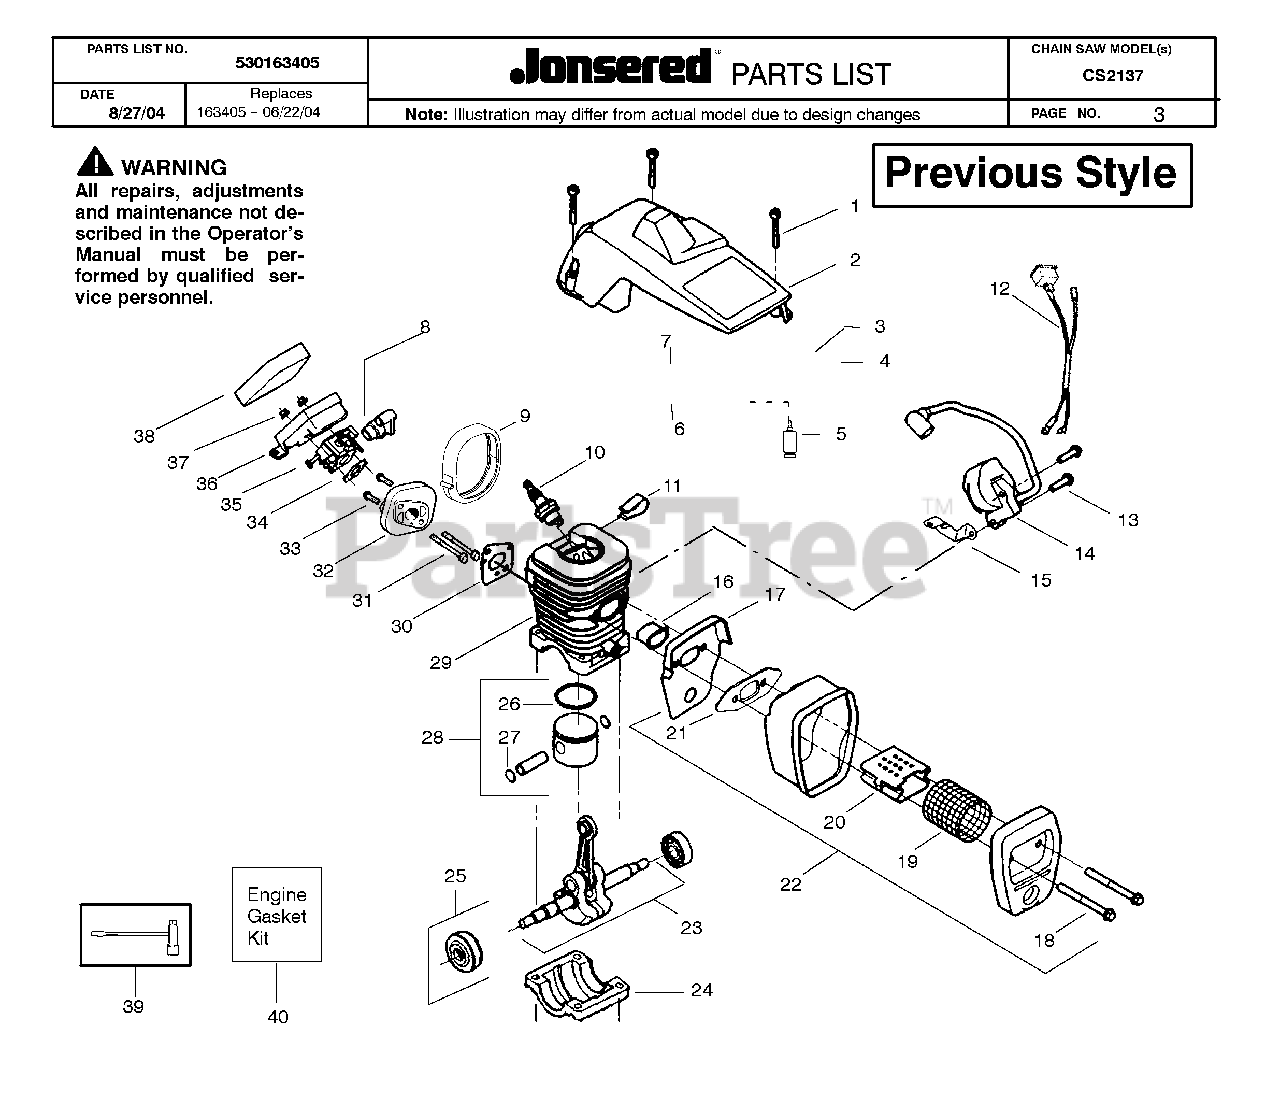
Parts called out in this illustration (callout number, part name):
2	CYL SHIELD ASSY
5	FUEL PICK-UP ASSY
8	GROMMET-CARB ADJUST
10	SPARK PLUG (RCJ-7Y)
12	WIRE HARNESS ASS'Y
14	MODULE-IGNITION
15	GROUND STRAP
16	HEAT INSULATOR
20	FLAME PROTECTION
22	MUFFLER
23	CRANKSHAFT
25	BEARING & SEAL ASSEMBLY
26	RING-PISTON
27	C-CLIP,PSTN PIN 36/41
29	KIT-CYLINDER
32	PARTITION
38	AIR FILTER
39	SCRENCH
530038317	LIMITER CAP (LOW-BLUE)
530047630	DECAL STOP
530069722	CARBURETOR
530071621	KIT-CARBURETOR (WT-625)
